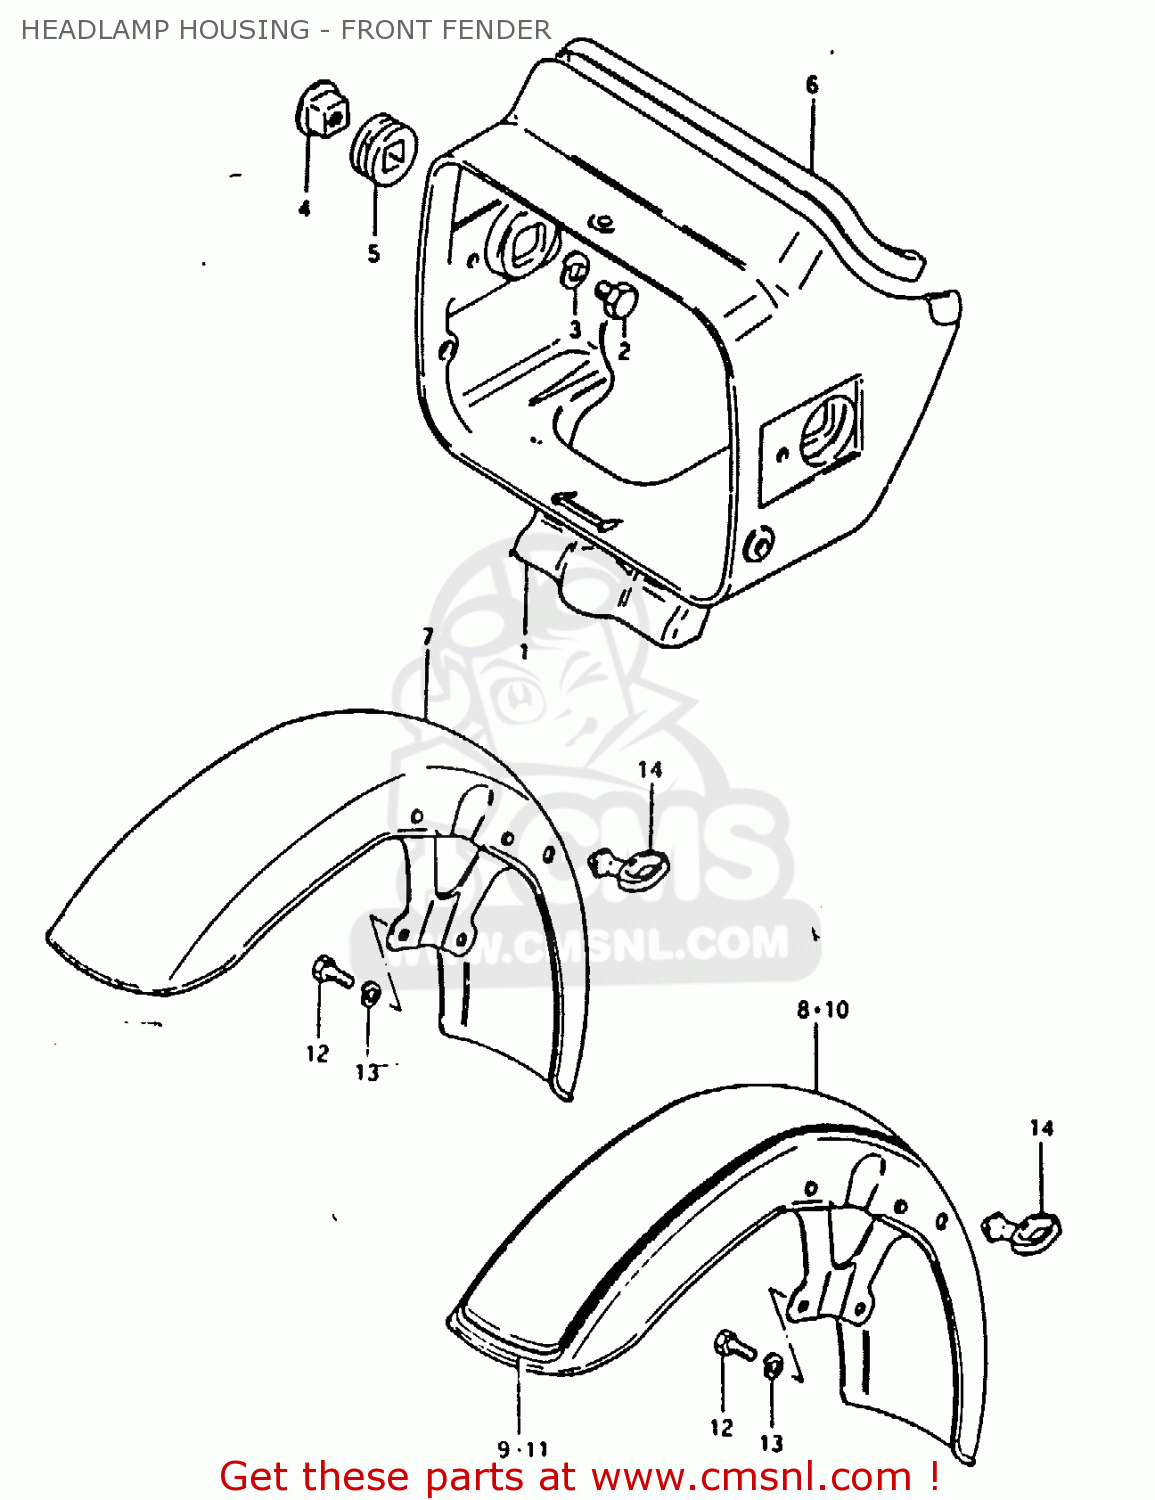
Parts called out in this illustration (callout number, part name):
1	HOUSING, HEADLAMP
2	BOLT
3	LOCK WASHER
4	SPACER,HEADLAMP HOUSING
5	CUSHION,HEADLAMP HOUSING
6	MOLDING,HEADLAMP HOUSING
8	FENDER, FRONT
9	TAPE,FRONT FENDER
10	FENDER, FRONT
11	TAPE
12	BOLT
13	LOCK WASHER
14	GUIDE,CABLE
